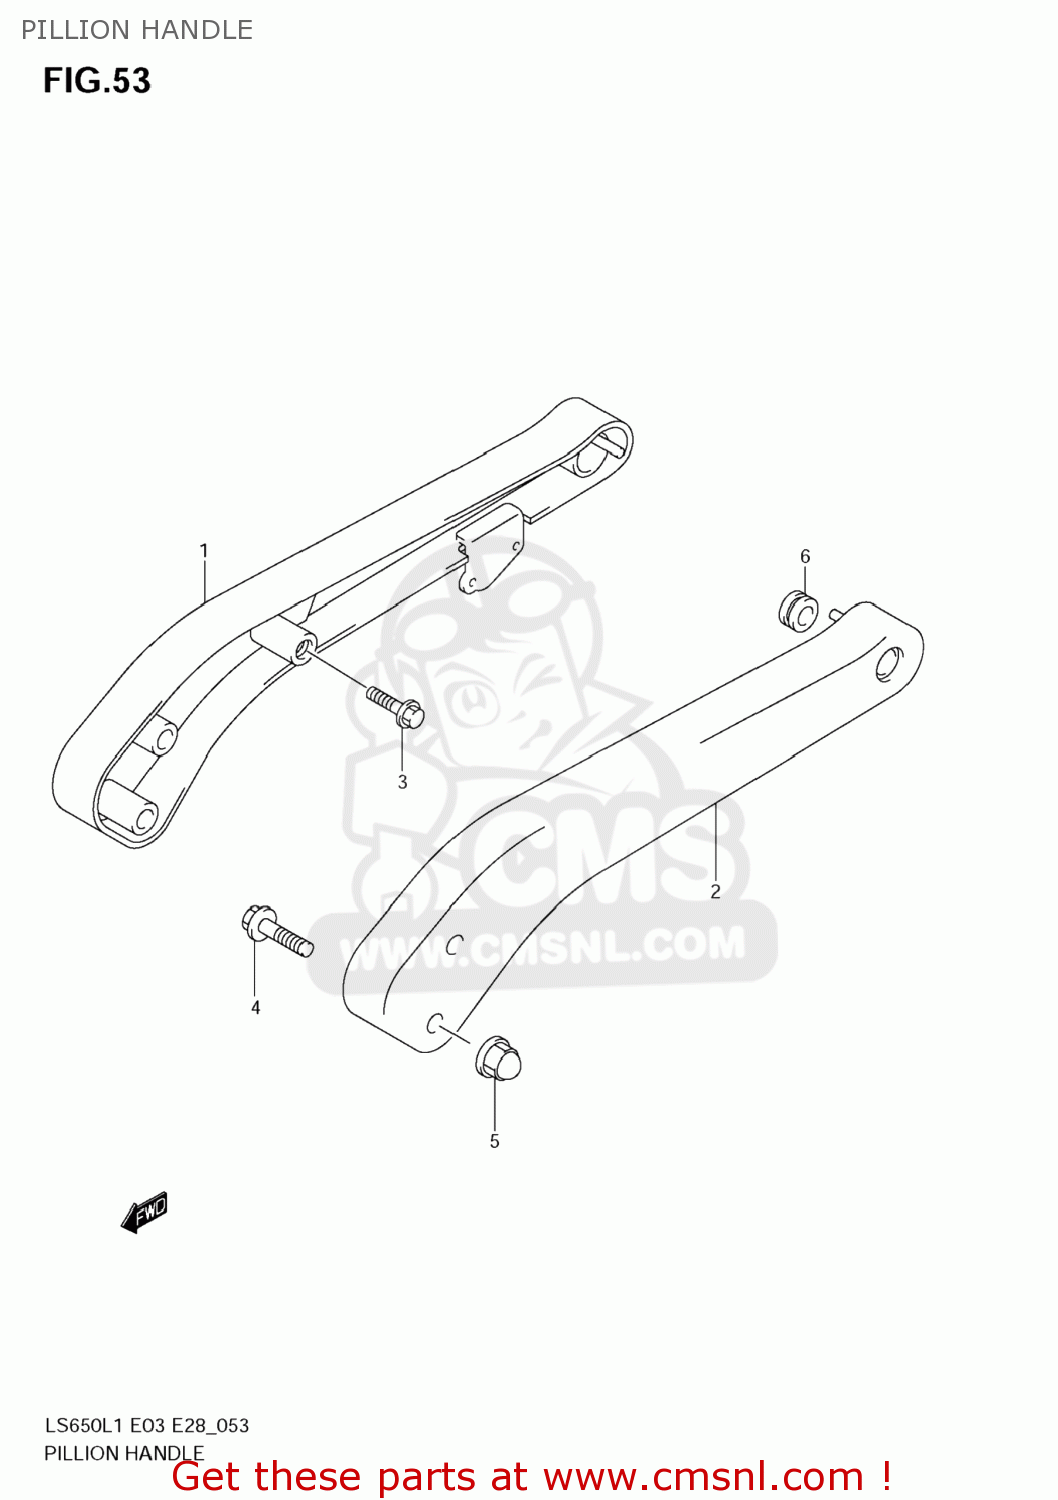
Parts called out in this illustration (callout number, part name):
1	HANDLE,PILLION RIDER,R
2	HANDLE,PILLION RIDER,L
3	BOLT
4	BOLT
5	NUT
6	CUSHION
